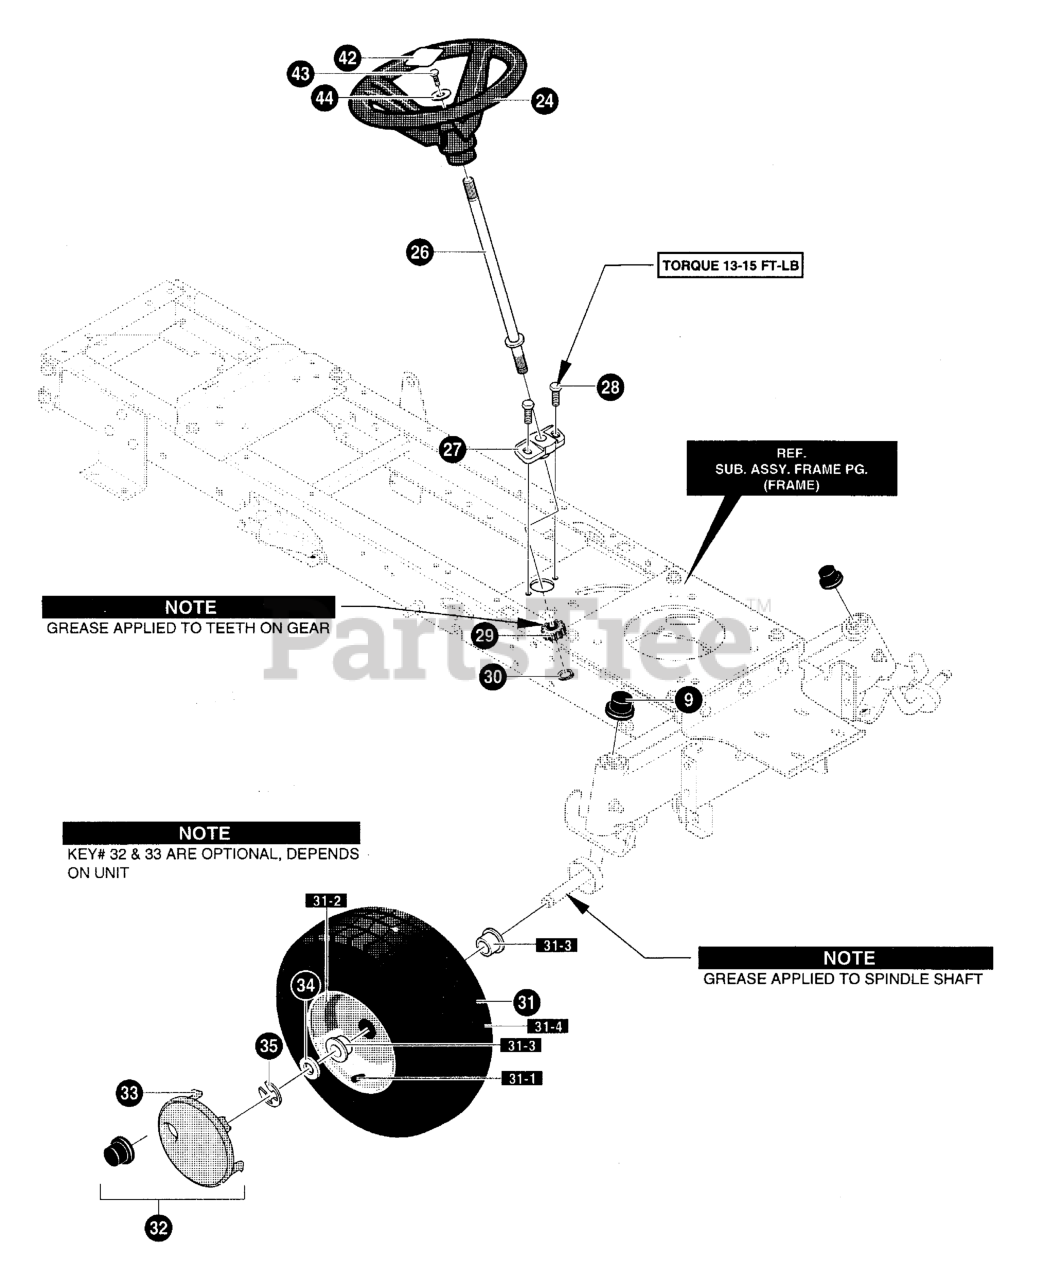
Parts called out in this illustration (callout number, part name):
9	DUST HUB CAP
24	STEERING WHEEL
26	SHAFT, STEERING
27	BEARING-LOWER
28	SCREW, 5/16-18 x 0.75
29	GEAR PINNION
30	RING, RET E.
31	TIRE&RIM, 15X6.0-6
31-1	VALVE STEM
31-3	BEARING
31-4	TIRE, 15X6X6
34	WASHER, FLAT .765 x 1.62 x .065
35	E-RING
42	INSERT, STEERING WHEEL HUB
43	SCREW, 1/4-20X.75 HHC
44	WASHER, FLAT .281X1.25X.06
